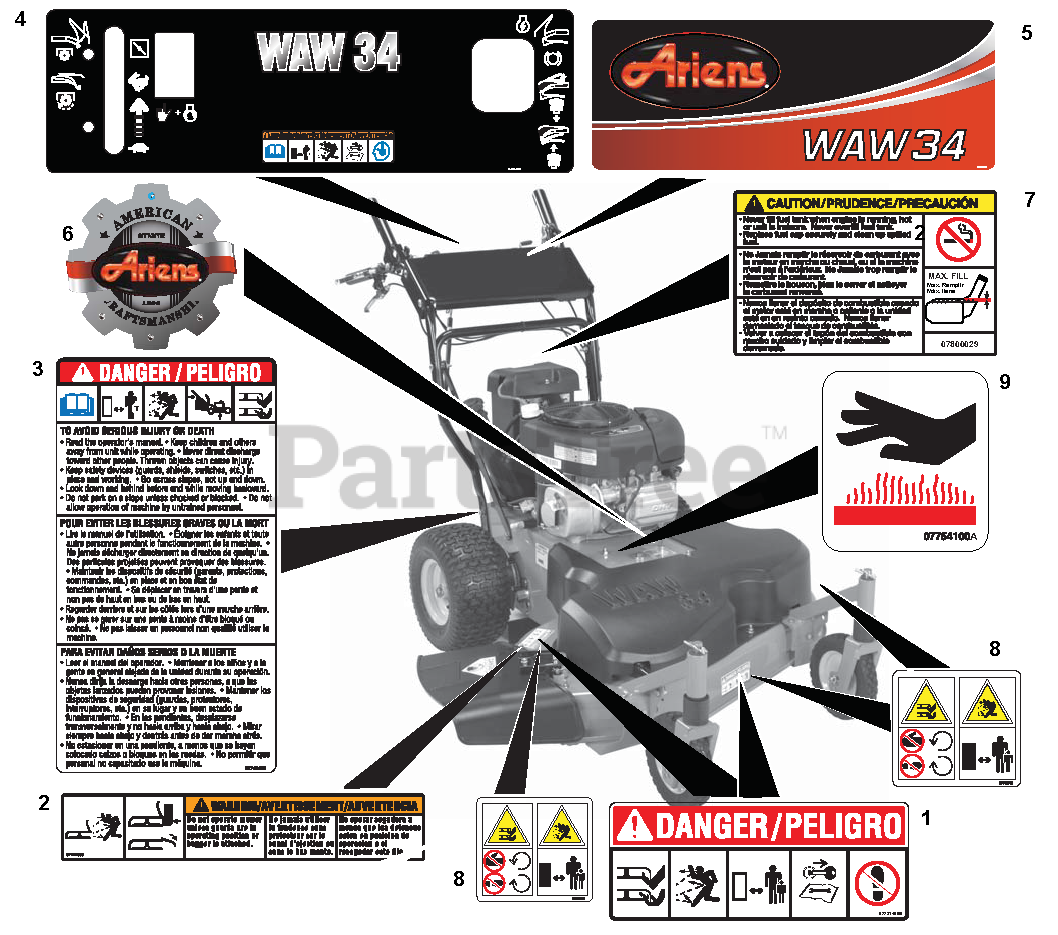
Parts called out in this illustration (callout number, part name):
1	DECAL, MOWER PAN DANGER
2	DECAL, WARNING
3	DECAL, BILINGUAL DANGER
4	DECAL, CE WAW OPERATIONAL
5	DECAL,WAW 34 ARIENS DASH
6	Decal, Gravely Heritage, Large
7	DECAL-FUEL, WARNING
8	DECAL, CE DECK
9	DECAL, HOT SURFACE
